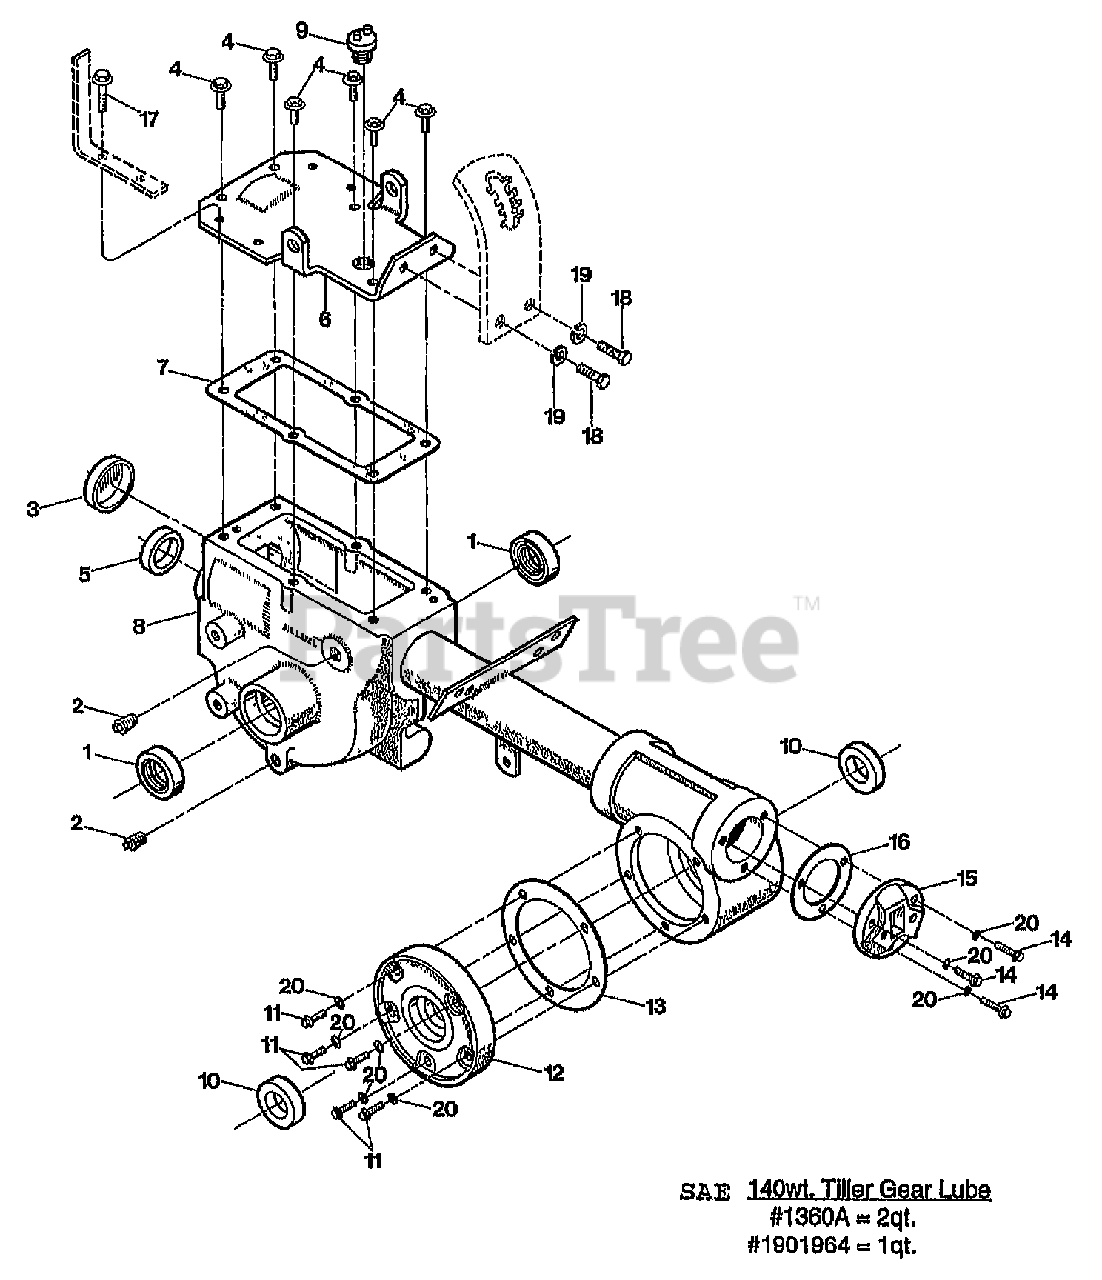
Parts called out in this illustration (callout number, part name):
1	SEAL-OIL WHEELSHAFT
2	PLUG-PIPE 1/4 NPT
3	SEAL-BORE
4	SCR-HFLK 5/16-18X.75 ZP
5	SEAL-PINION SHAFT PT/85030/00
6	KIT-COVER TRANS W/HDW (INCL. FOUR OF NO. 17 & TWO EA OF NO'S 18-19)
7	GASKET-TRANS COVER
8	ASSM-TRANS A-UNIT JR W/UP
9	PLUG-OIL FILL 3/4-10
10	SEAL-TILLER SHAFT
11	SCR-HH 1/4-20X.625
12	COVER-TILLER HSG MACH (INCL. 5 SCREWS NO. 11)
13	GASKET-TILLER COVER (FITS ALL COVERS)
14	SCR-HFLK 1/4-20X.875
15	CAP-REAR #1115
16	GASKET-BRG COVER
17	SCR-HFLK 5/16-18X1.00 ZP
18	SCR-HH 3/8-16X.75 G5 ZP
19	WASHER-LK .375 @ DEPL
20	WASHER, NYLON. NOT REUSABLE.
